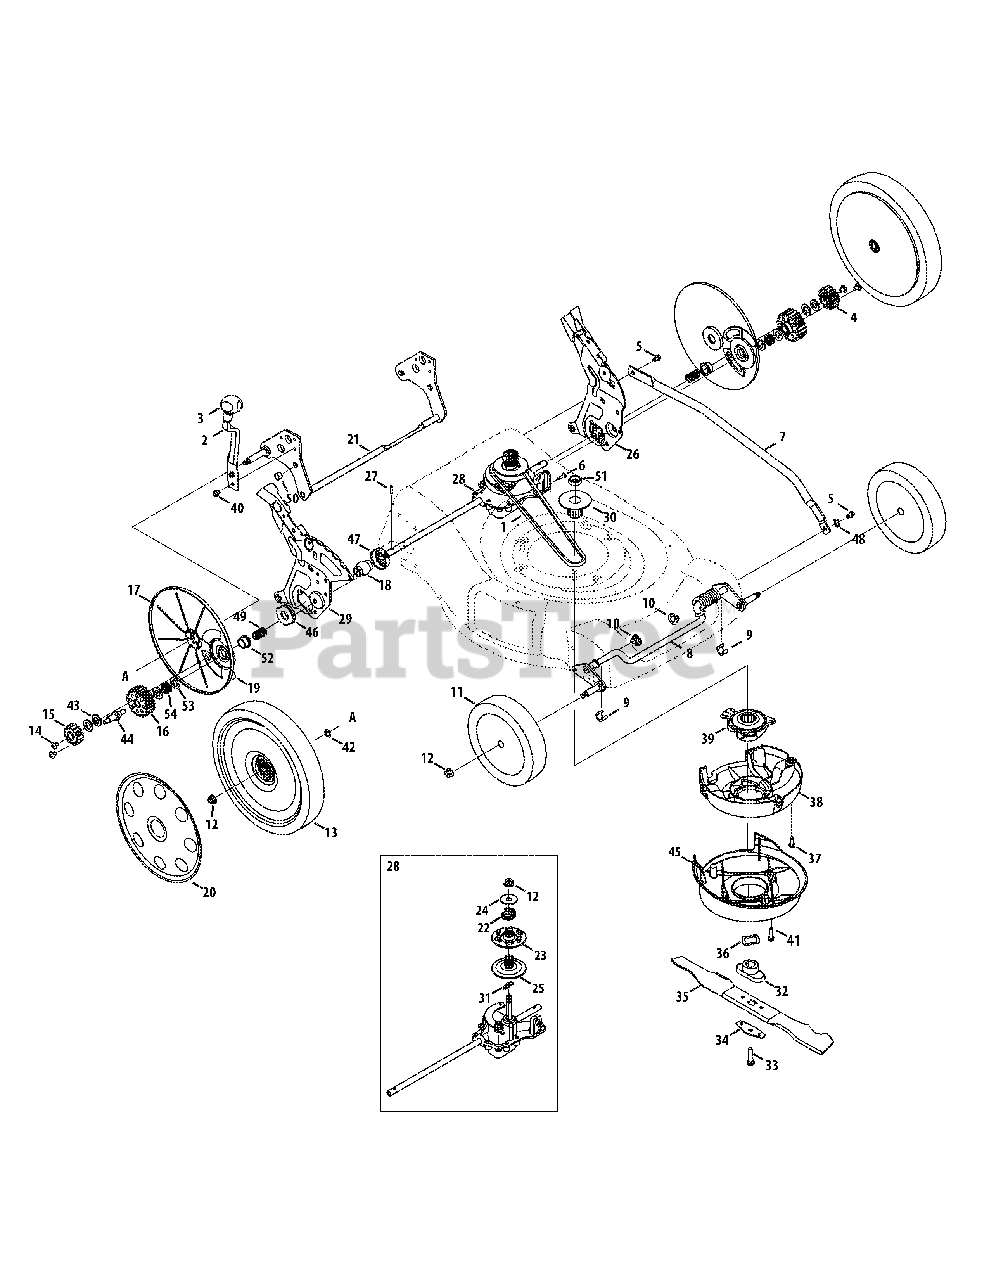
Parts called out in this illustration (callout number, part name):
2	Spring Lever
3	Height Adjuster Knob
4	Spur Gear, 16T - LH
5	Shldr. Screw, 1/4-20 x 0.50
6	Screw, 1/4-15 X .750
7	Cross Bracket
8	Front Bracket Assembly
9	Clip Spacer
10	Split Hex Flange Bearing
11	Front Wheel
12	Flange Lock Nut, 3/8-16
13	Rear Wheel
14	Screw, 1/4-20 x .39
15	Spur Gear, 16T - RH
16	Gear, Spur, 23T
17	Wheel Dust Cover
18	Bearing Sleeve
19	Dust Cover Seal Plate
21	Rear Bracket Assembly
22	Compression Spring
23	Upper Pulley
24	Flat Washer, .442 x 1.38 x .060
25	Lower Pulley
26	Handle Bracket Assembly LH
27	Dowel Pin
28	Transmission Assembly
29	Handle Bracket Assembly RH
30	Pulley, Half
31	Extension Spring
32	Blade Adapter
33	Screw, 3/8-24 x 1.50
34	Blade Bell Support
35	21" Mulching Blade
36	Washer, Wave, 1.5 x 1.0 x .029
37	TT Screw, 1/4-20 x .500
38	Engine Baffle
39	Lower Pulley Assembly
40	Screw, TT, 1/4-20 x .375
41	Screw, 1/4-15 x 1.25
42	Washer, Spring, .500 x 1.00 x .022
43	Washer, Flat, .510 x 1.00 x .060
44	Shf., .500 Dia.
46	Bearing Support
47	Bearing Retainer
48	Washer, Wave, .385 ID x .598 OD
49	Spring, Comp., .63 OD x 1.00 Lg.
50	Spacer, .690 x .870 x .150
51	Spcr., 25mm x 1.375
52	Spcr.,Flg., .51 ID x .58 OD
53	Washer, Flat, .508 x 1.00 x .020
54	Spring, Wave
